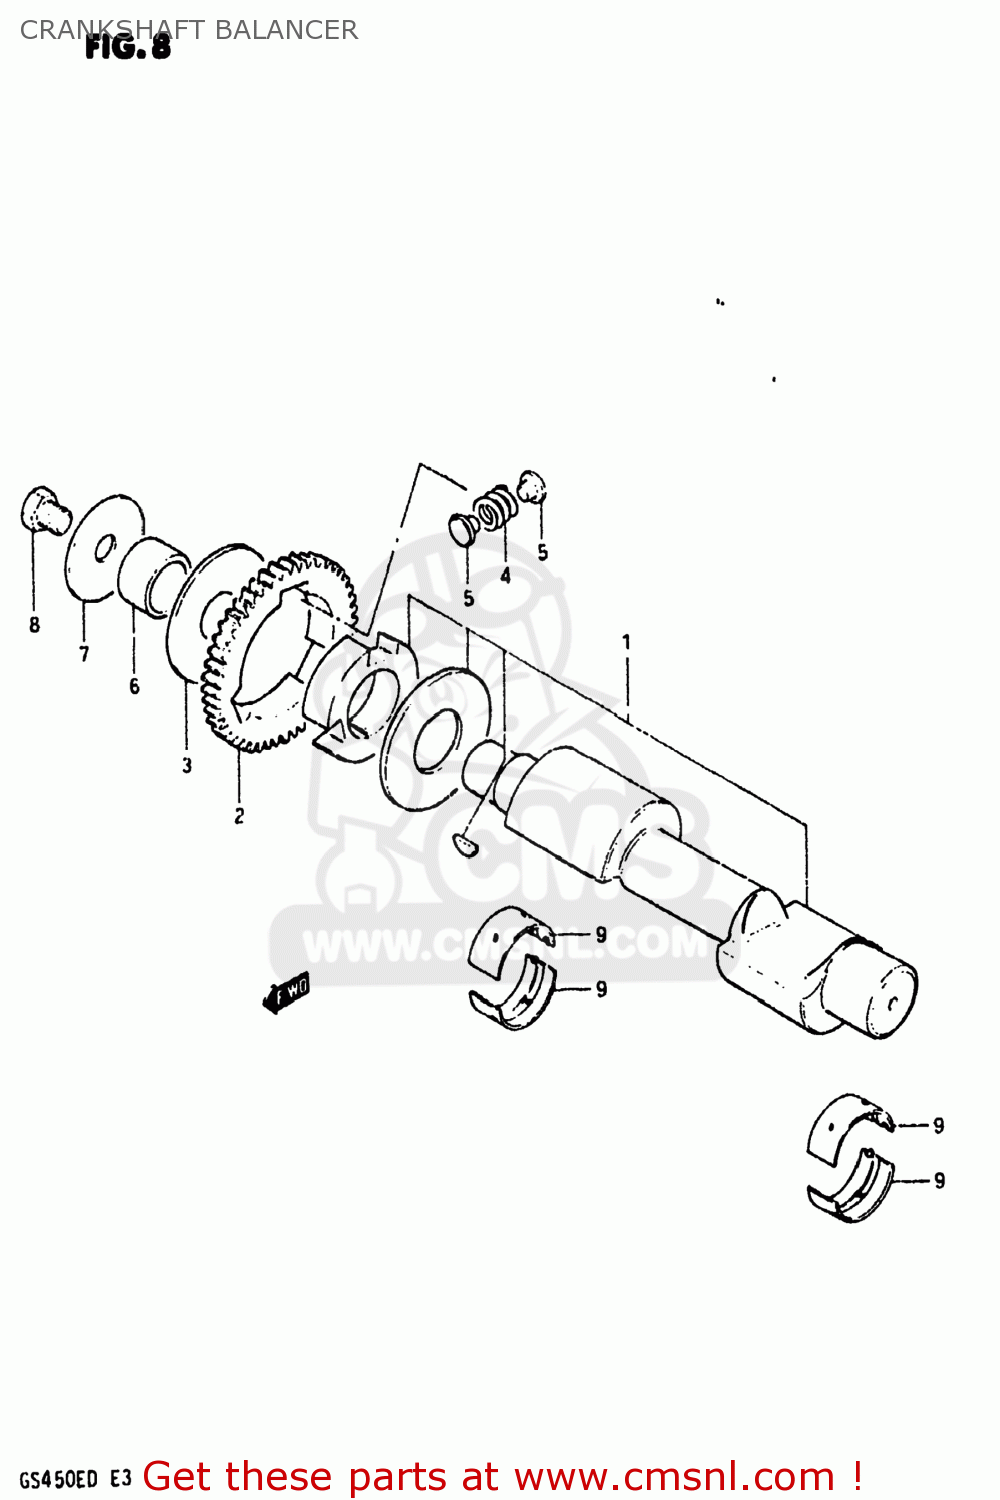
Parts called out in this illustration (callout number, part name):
1	BALANCER,CRANKSHAFT
2	GEAR,CRANK BALANCER DRIVE
3	WASHER
4	SPRING
5	PIN
6	SPACER
7	WASHER(12X50X3)
8	BOLT
9	METAL CRANKSHAFT
